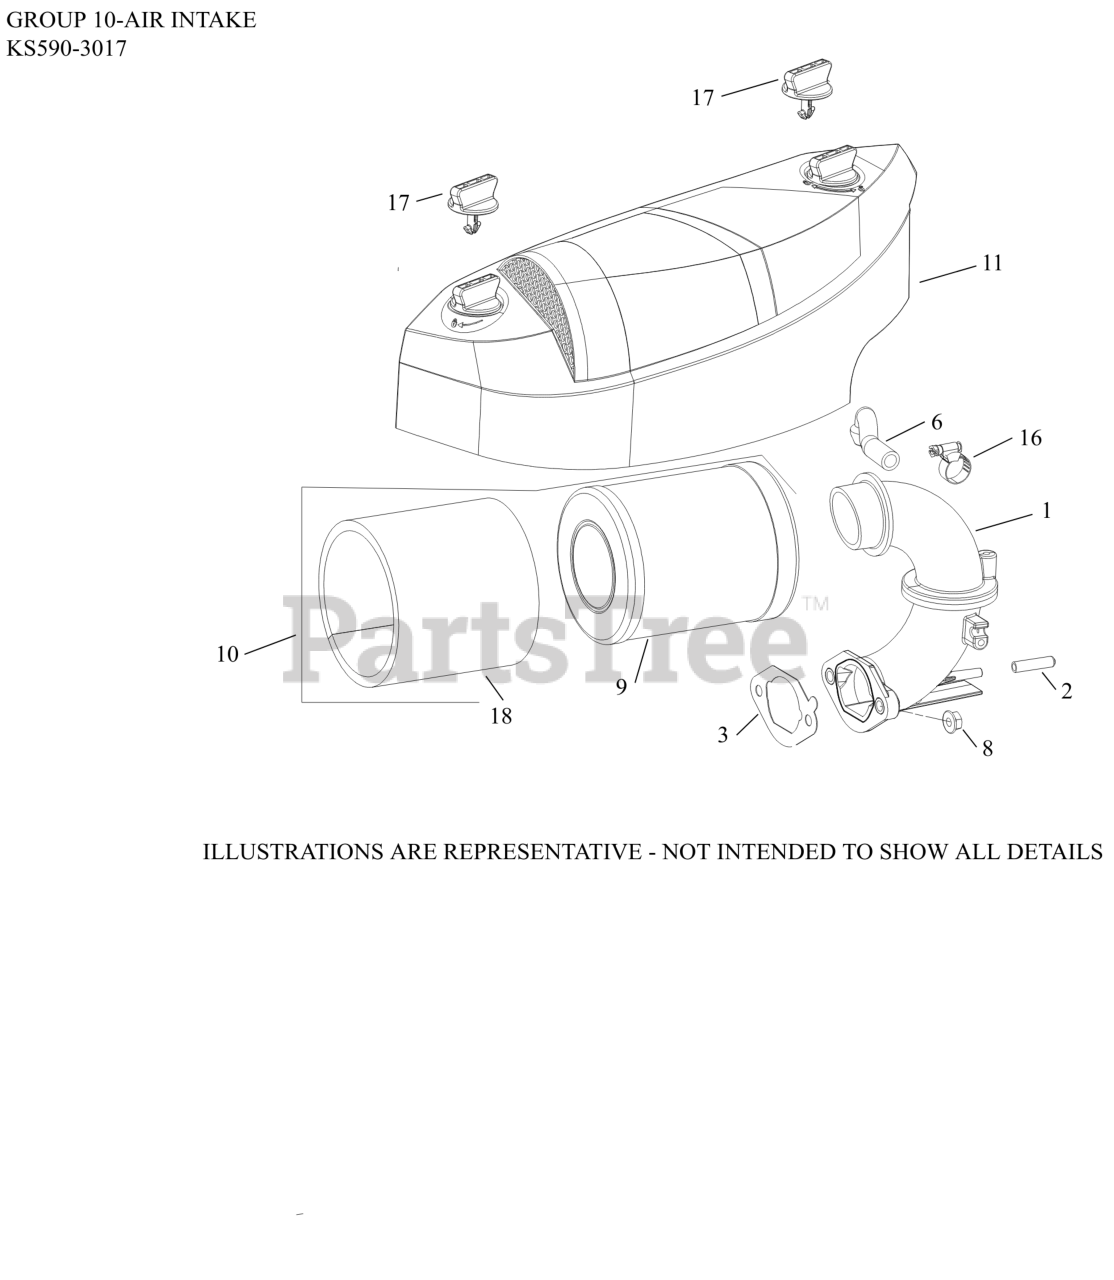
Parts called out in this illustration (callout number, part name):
1	ADAPTER, AIR CLEANER ASSY
2	CAP, MASKING
3	GASKET, CARBURETOR
6	HOSE, BREATHER
8	NUT, FLG M6X1.0
9	ELEMENT, AIR FILTER
10	AIR FILTER KIT (PRO)
11	COVER, AIR CLEANER ASSEMBLY (PRO)
16	CLAMP, HOSE (KM)-USE 25 237 31-S
17	KNOB, AIR CLEANER COVER
NI	ELEMENT, PRE-CLEANER
